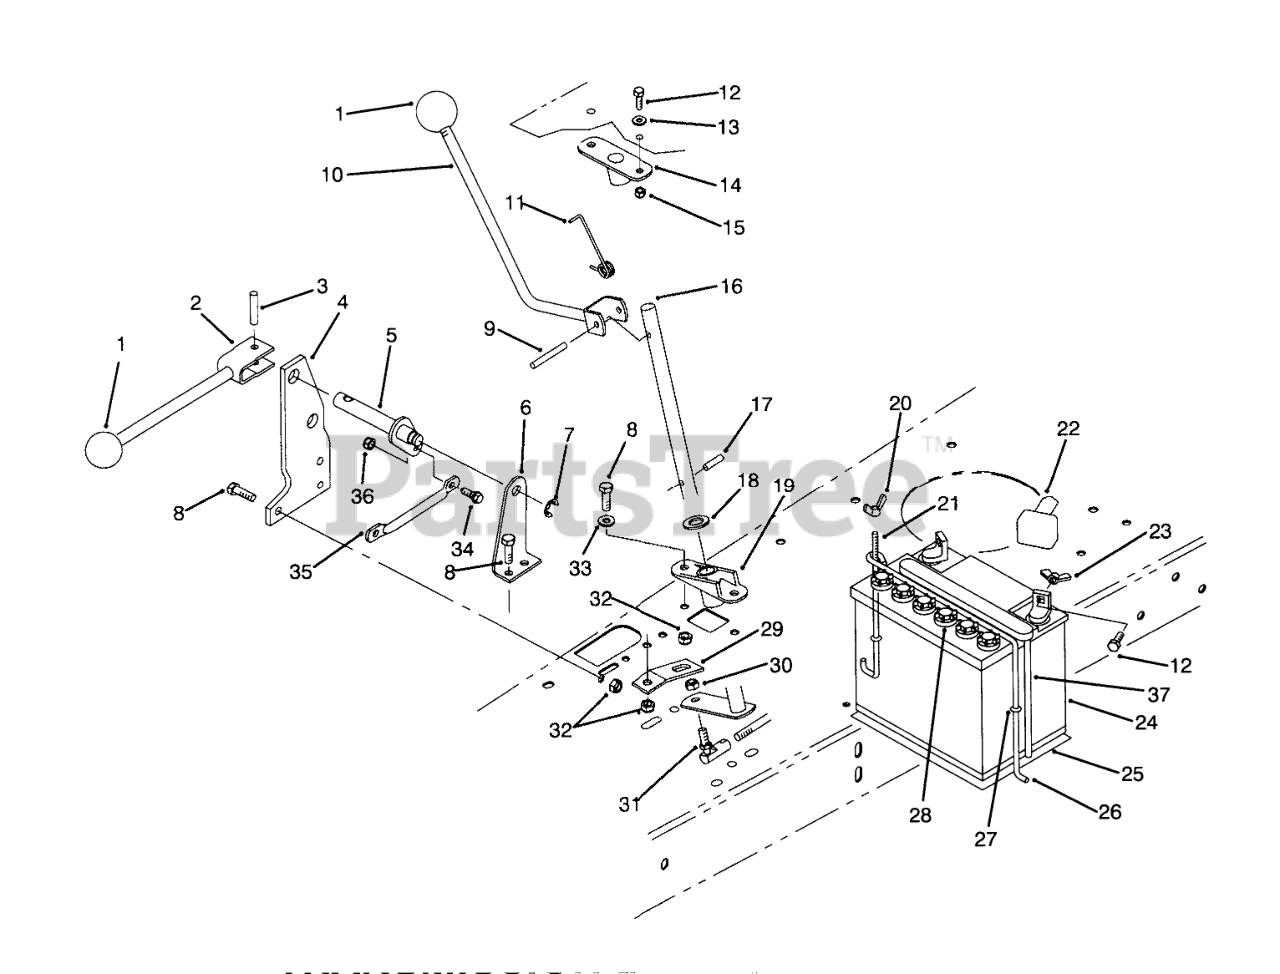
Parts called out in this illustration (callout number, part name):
2	Lever W.A.-Engage
3	PIN-ROLL
4	Pivot-Outer
5	PIVOT SHAFT WA
6	Bracket-Pivot, Inner
7	RING-RETAINING, EXTERNAL
8	SCREW-HH
9	PIN-ROLL
10	Lever W.A.-Shaft
11	SPRING-TORSION
12	SCREW-HH
13	WASHER-FLAT
14	SUPPORT-SHIFT SHAFT
15	NUT-LOCK, NI
16	SHAFT-SHIFT
17	PIN-SPRING
18	WASHER-THRUST
19	SUPPORT-LOWER SHIFTER
20	NUT-WING
21	POST-BATTERY
22	BOOT-TERMINAL
23	NUT-WING
24	Battery-12 Volt (Incl. Ref. #28 & 37)
25	PAD-SKID, ANTI
26	HOLDDOWN-BATTERY
27	O-RING
28	CAP-BATTERY
29	RETAINER-TRACTION SPRING
30	NUT-LOCK
31	JOINT-BALL
32	NUT-LOCK, NI
33	WASHER-PLAIN
34	SCREW-SHOULDER
35	LINK-BELLCRANK
36	NUT-HEX
37	TUBE-BATT DRAIN/80-2600
